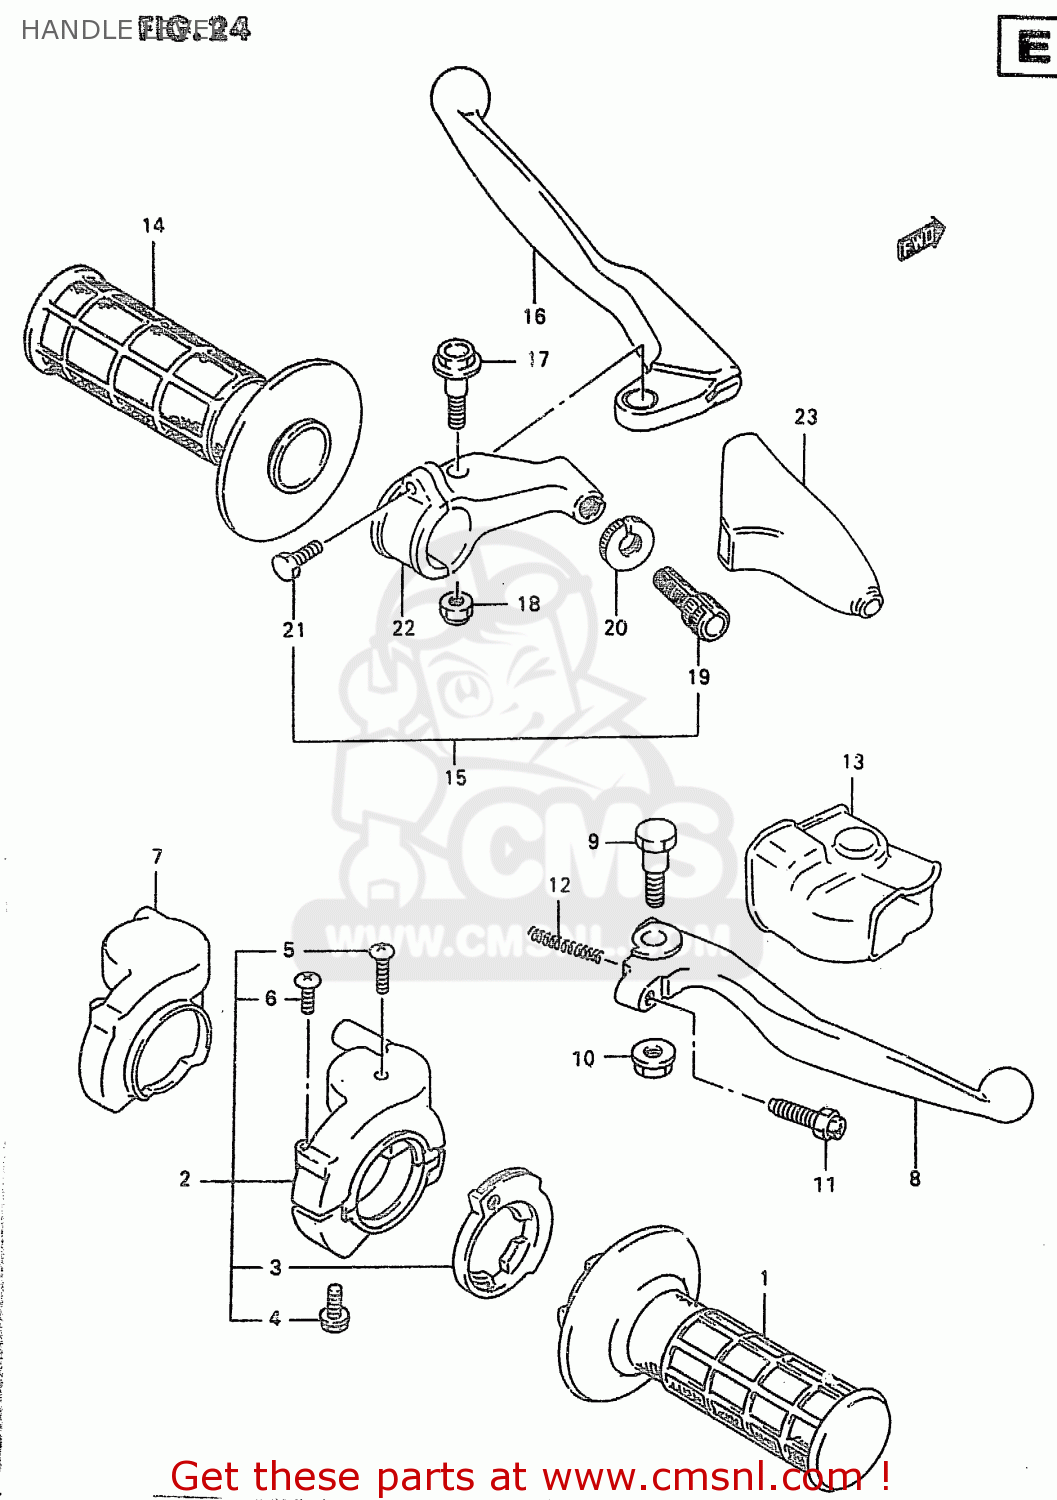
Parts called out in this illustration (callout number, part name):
1	GRIP,THROTTLE
2	CASE ASSY,THROTTLE
3	ROTOR,THROTTLE
4	BOLT 6X25
5	SCREW,UPPER
6	SCREW
7	COVER,THROTTLE CASE
8	LEVER,BRAKE
9	BOLT,BRAKE LEVER
10	NUT,BRAKE LEVER
11	BOLT,ADJUSTER
12	SPRING,RETURN
13	COVER,BRAKE LEVER
14	GRIP,L
15	LEVER ASSEMBLY,CLUTCH
16	LEVER,CLUTCH
17	BOLT,LEVER
18	NUT 6MM
19	ADJUSTER,WIRE
20	NUT,LOCK
21	BOLT
22	BRACKET,LEVER HOLDER
23	COVER,CLUTCH LEVER
